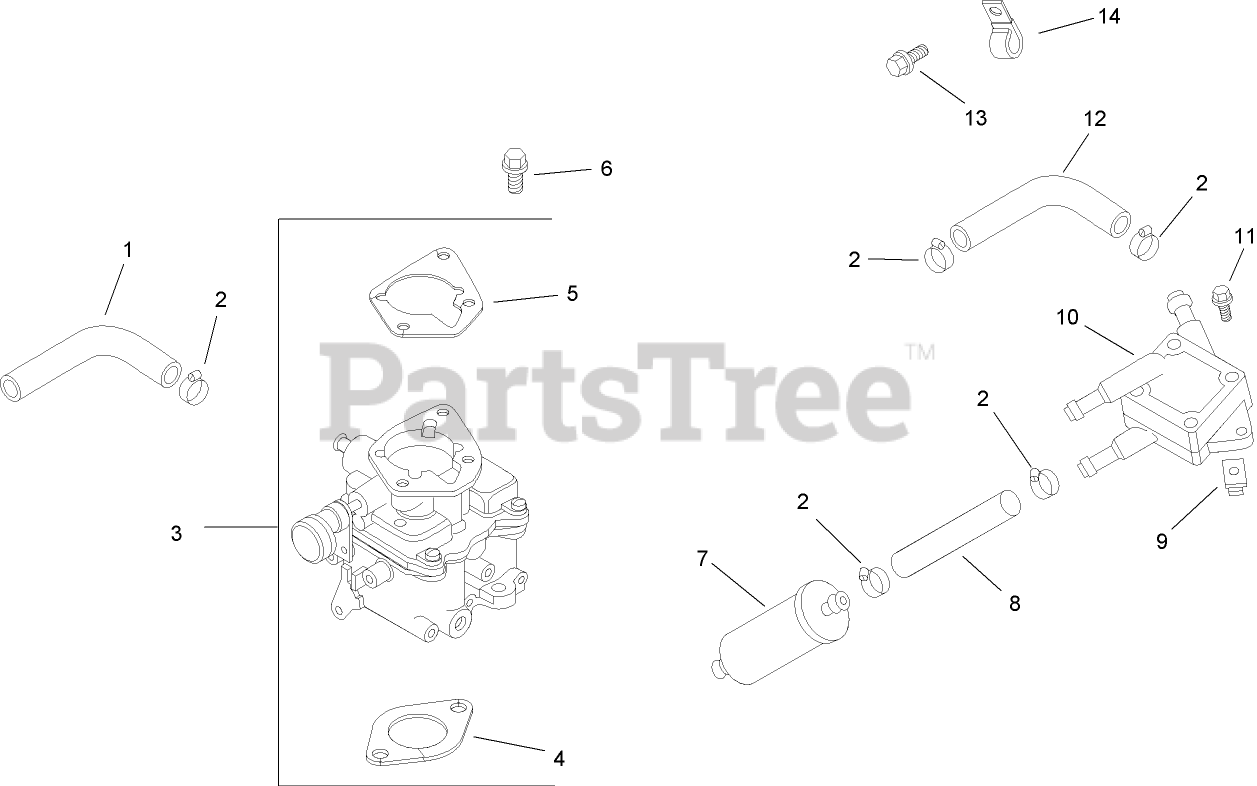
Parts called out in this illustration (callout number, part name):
1	HOSE-FUEL, LOW-PERMEATION
2	CLAMP-HOSE, SPRING (1/2)
3	Carburetor Kit
4	Gasket-Carburetor
5	GASKET-BASE, AIR CLEANER
6	SCREW-FLANGE (M6X1.0X30)
7	FILTER-FUEL
8	LINE-FUEL (24.0 CUT TO LENGTH)
9	Nut-Plastic
10	PUMP-FUEL
11	SCREW-TAP (M6X1.7X18)
12	Line-Fuel, Flexible (15.5)
13	CLIP-CABLE
14	Screw-HF (M6x1.0x12)
